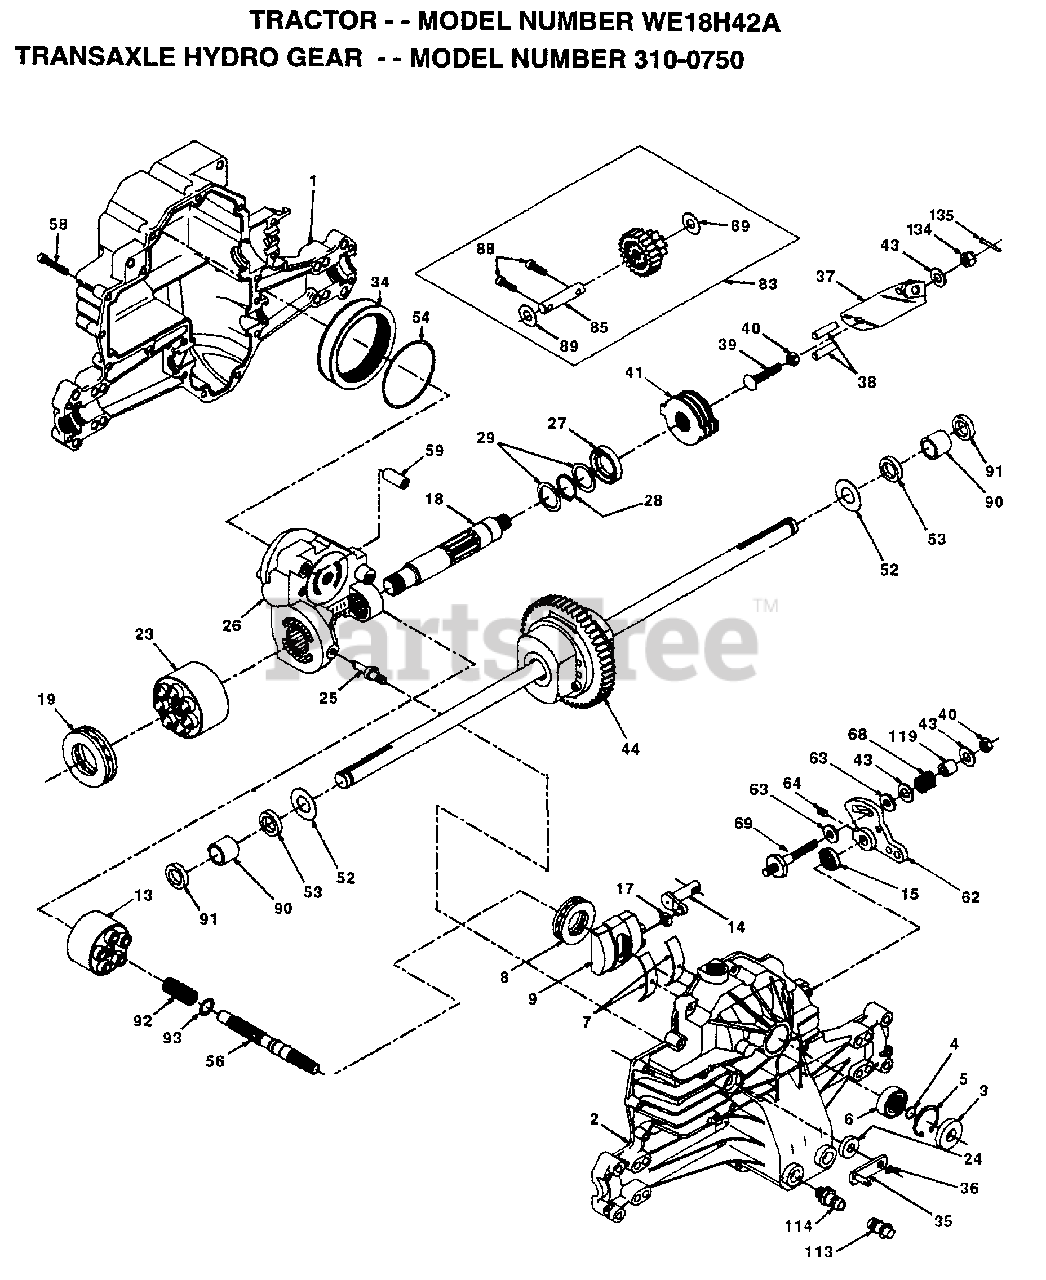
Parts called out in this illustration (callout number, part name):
1	HOUSING.L.50074RM
2	HOUSING.UP.70125
3	SEAL.9008000-0128
4	RING.RET.2003016.
5	RING.RET.2003052.
6	BEARING.(50552)42X68X16
7	CRADLE- 2003023.
8	BEARING.2003044.
9	SWASHPLT.2003087.
13	BLOCK.CLYN.70079.
14	ARM.TRUN.2003005.
15	SEAL.9008000-0126
17	GUIDE.2000015.
18	SHAFT.MOTOR.50115
19	BEARING.THS.50019
23	BLOCK.CYLIN.70082
24	SEAL.LIP.45074
25	ACTUATOR.2003555
26	KIT.CENTER.70133
27	SEAL.LIP.45075
28	RING RETAIN 50007
29	WASHER.44872
34	ELEMENT.OIL.44964
35	ARM.BYPASS.50270
36	RING.RETAIN.44870
37	ARM.ACTUAT.23710
38	PIN.ACTUAT.44891
40	NUT.LOCK.HX.50108
41	KIT.BRAKE.70135
43	WASHER HYD 44130
44	DIFFERENTIA.70130
52	WASHER.HYD.50152
53	SEAL.HYDRO.45076
54	O RING.HYD.45077
56	SHAFT.INPUT.50005
58	BOLT.1/4-20.44876
59	PIN.HYDRO.50002
62	ARM.CONTROL.50254
63	PUCK.DAMPER.50281
64	SCREW.SET.50018.
68	SPRING.HYD.50277
69	STUD.5/16-24.DANA
83	JACKSHAFT/PINION GEAR.70132
85	JACKSHAFT.50086
88	SCREW.CAP.50154.
89	WASHER.HYD.50132
90	BEARING.SLV.50118
91	SEAL.WIPER.50941
92	SPRING.2003014.
93	WASHER.2003017
113	CAP.VENT.70109
114	O-RING.ASM.70110
119	SPACER.HYD.50278
134	NUT.CAS.HYD.44142
135	PIN.COT.HYD.44101
